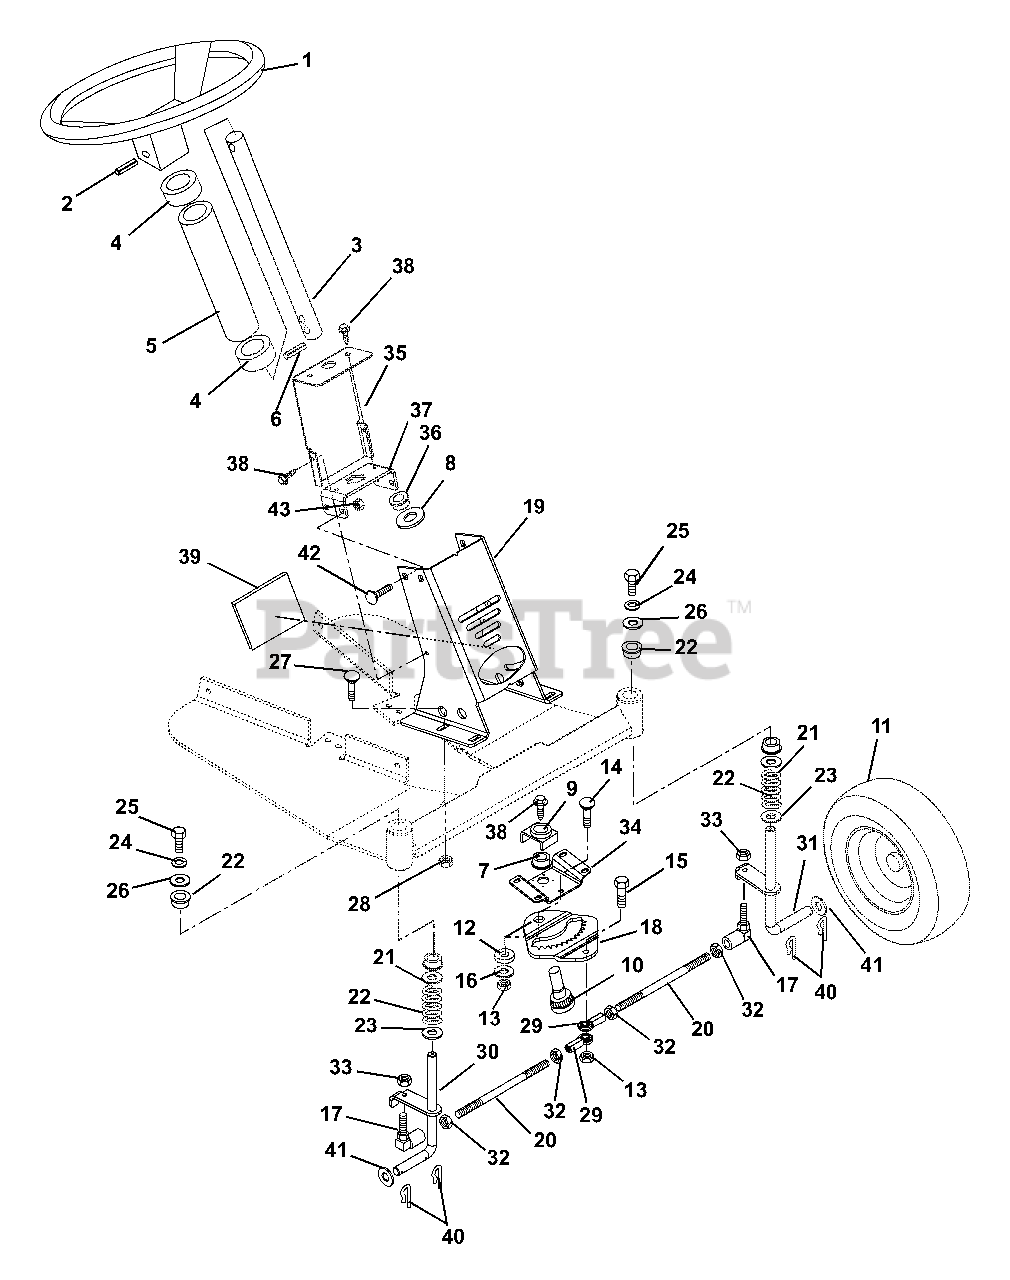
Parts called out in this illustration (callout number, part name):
1	STEERING WHEEL 13"
2	PIN-ROLL .250X1.75
3	STEERING SHAFT
5	TUBE 1.865 X 2.00 X 11.33
6	PIN-ROLL .188X.75
7	BSHG-FLG .625X1.156X.375 SI
8	WSHR-HDND-STL-THR.515X.97X.062
9	RETAINING PLATE
10	PINION
11	T/WHL ASSY
11	TIRE 4.10/3.50-4
11	BSHG-FLG .750X1.380X.750X1.557
12	STEER GEAR SPACER .38X.75X.269
13	NUT-LK-TOP-FLG .38-16 BLKZC
14	BLT-RDHDSQNK .38-16X1.00 G5BZ
15	@BLT-HEX .38-16X1.75 GR5 YWZC
16	WSHR-FL-STL .406X1.375X.135 YZ
17	BALL JOINT
18	STEERING GEAR
19	BOX, STEERING
20	STEERING LINK
21	SPRING, SUSPENSION
22	BUSHING-1"X.75"X1"
23	WSHR-FL-STL .700X1.47X.134 YWZ
24	@WSHR-LK .31X.078 REG YWZC
25	@BLT-HEX .31-18X.75 GR5 YWZC
26	WSHR-FL-STL .406X1.375X.135 YZ
27	BLT-RDHDSQNK .38-16X.75 G5BZ
28	NUT-LK-TOP-FLG .31-18 BLKZC
29	ROD END, .38 RH
30	WLDMT-SPINDLE (RH)
31	WLDMT-SPINDLE (LH)
32	NUT-JAM .375-24 YWZC
33	NUT-LK-NYL .375-24 W/INSR YWZC
34	STEERING GEAR SUPPORT
35	BRACKET, STEERING COLUMN
36	FLANGE BUSHING
37	SUPPORT-STEERING COLUMN
38	SCR-TAP .312-18X.50 HWH TR BL
39	COVER, LIGHT
40	PIN, SPRING CLIP
41	WSHR-FL-STL.755X1.375X.062YWZC
42	BLT-RDHDSQNK .31-18X.75 G5BZ
43	@NUT-LK-NYL .312-18 YWZC
